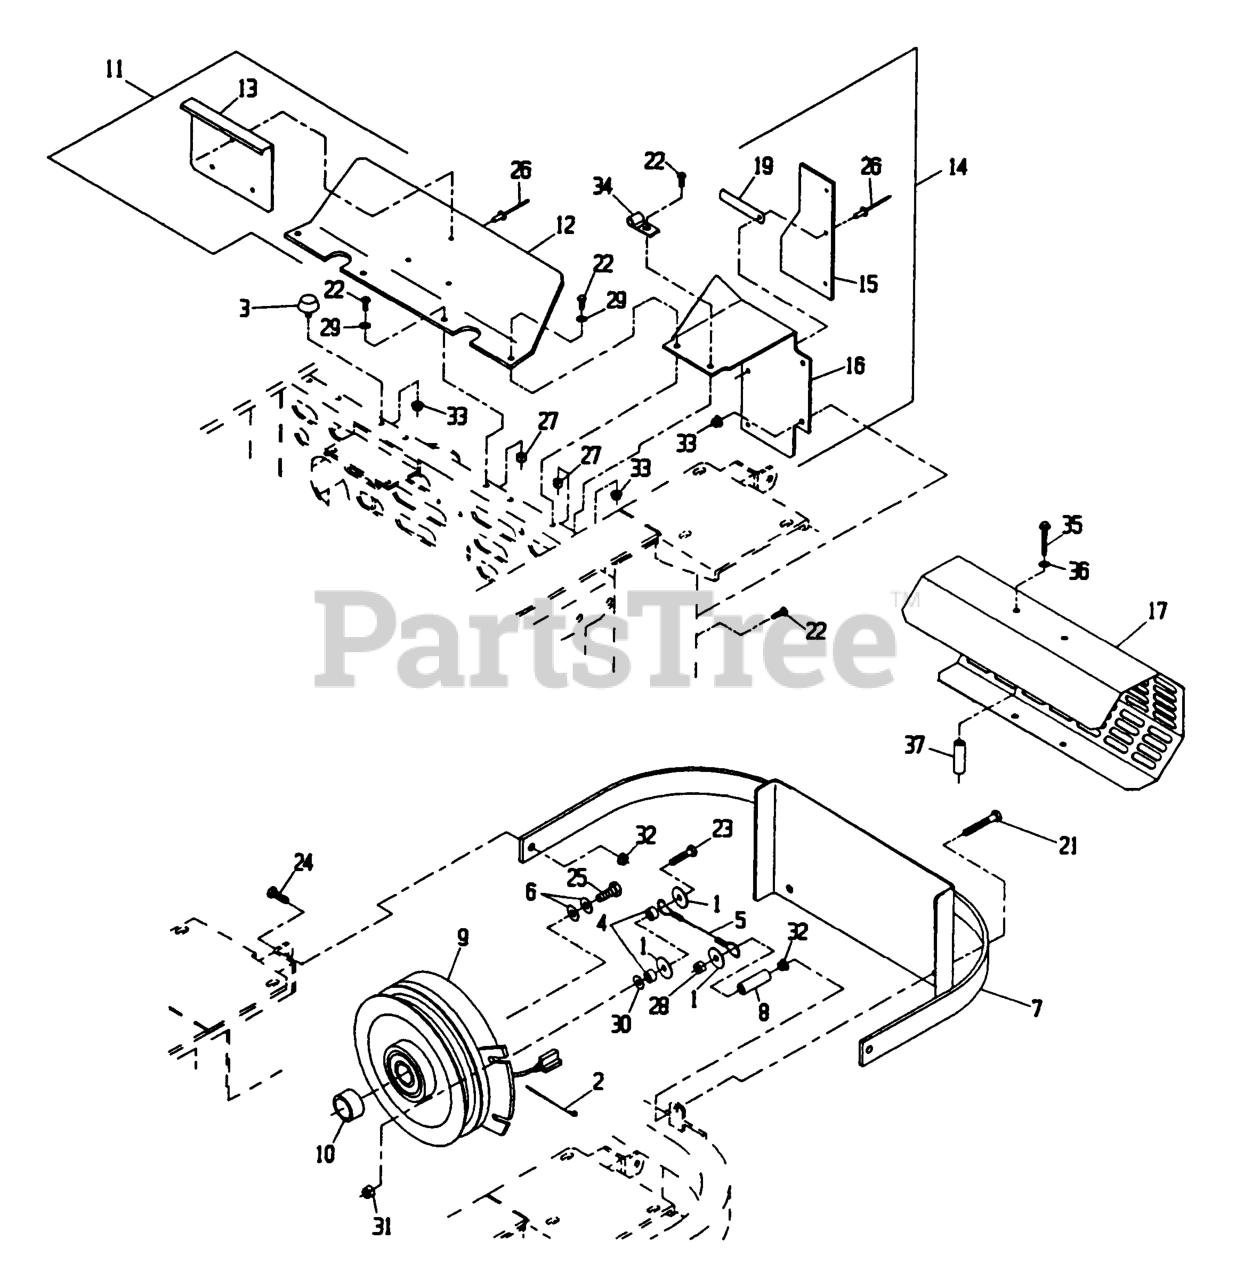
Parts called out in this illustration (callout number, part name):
2	TIE-PLASTIC
4	SPACER,CLUTCH ANCHOR
6	WASHER-SPRING
8	BUSHING-LEVER, LIFT
10	SPACER-CLUTCH
13	Shield, Lift
15	SHIELD-ENGINE
19	CLIP-BAFFLE, REAR
26	RIVET-POP
34	CLIP-LOOM
36	WASHER-SPRING
